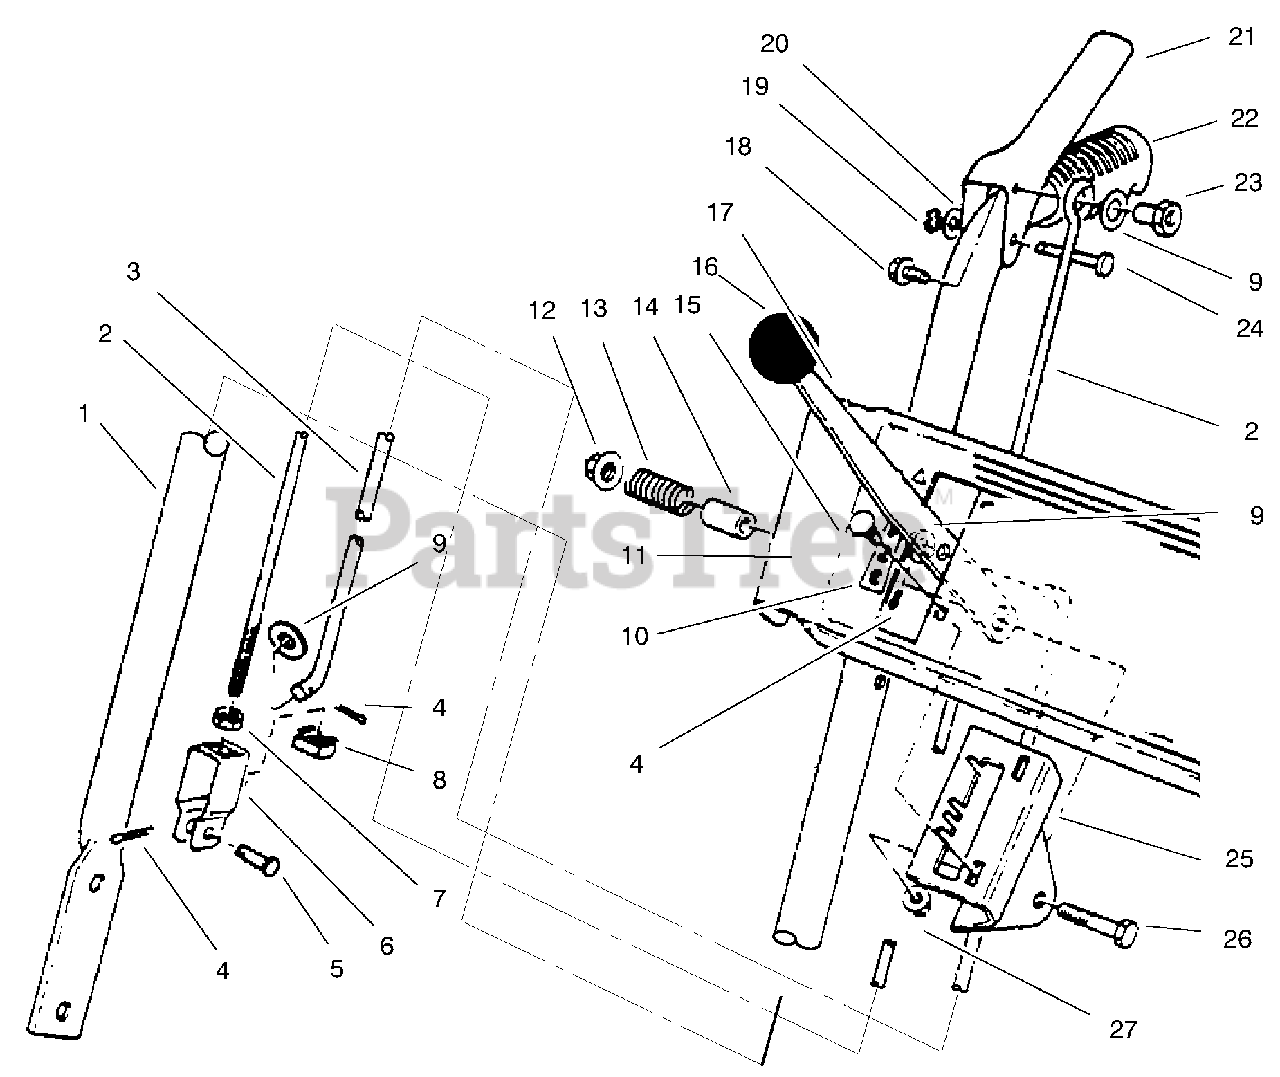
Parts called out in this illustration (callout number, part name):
1	Handle-Right
2	LINK-UPPER
3	ROD-SELECTOR, SPEED
4	PIN-COTTER
5	PIN-CLEVIS
7	NUT-JAM
8	NUT-RETAINED
9	WASHER-FLAT
10	ESCUTCHEON PLT B
11	DECAL - ESCUTCHEON
15	SCREW-CARR
17	SPEED SELECTOR B
18	SCREW-HHF
19	RING-CLIP
20	WASHER-FLAT
21	Handle-Control
22	GRIP-HANDLE
23	POST-LINKAGE MOUNTING
24	PIN-LEVER, CONTROL
25	Mount-Speed Selector
26	SCREW-HH
